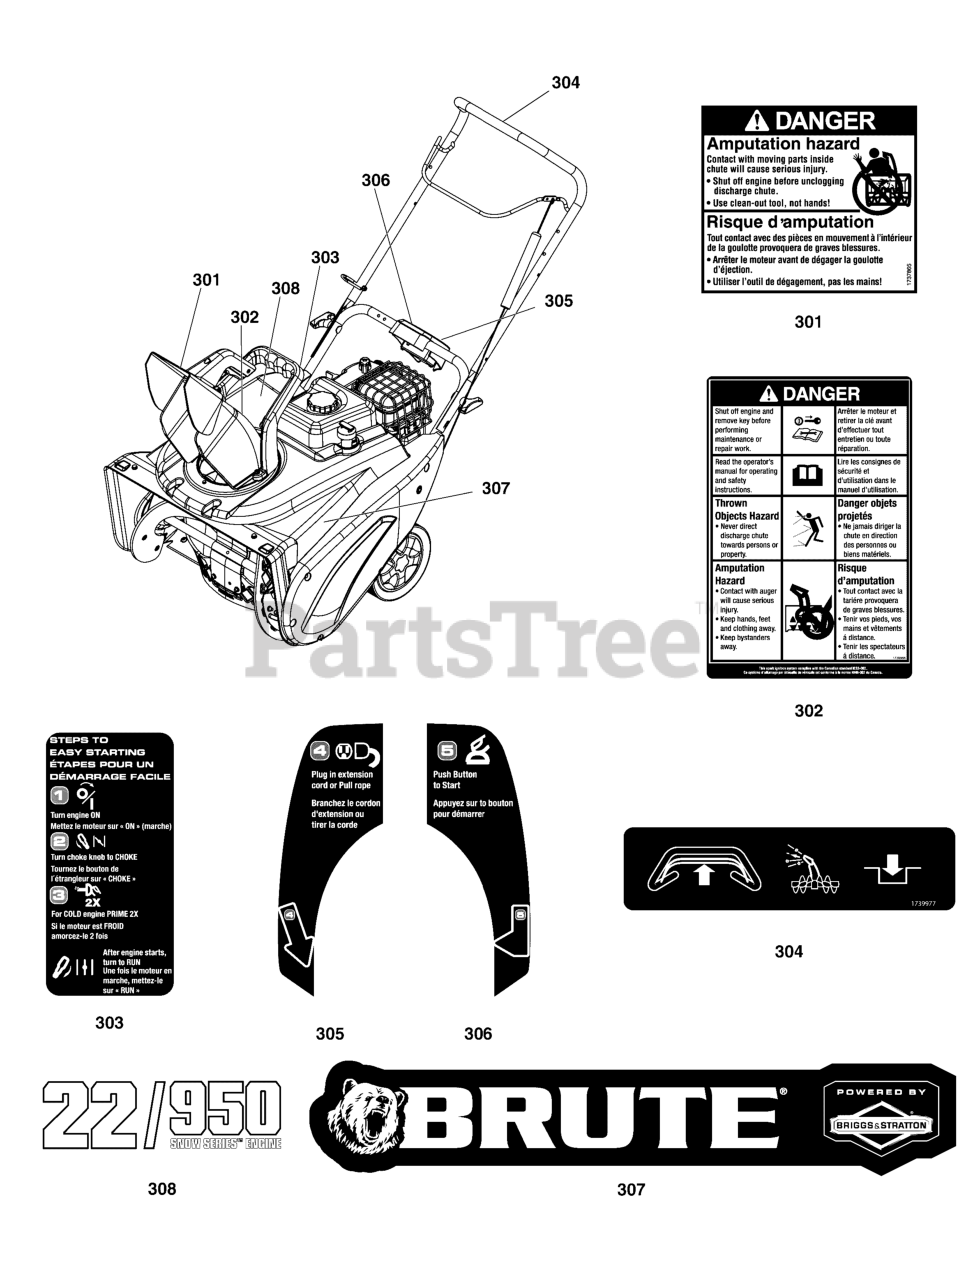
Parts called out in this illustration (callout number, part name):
301	DECAL, Danger Chute Warning, FR/ENG
302	DECAL, Chute, FR-EN
303	DECAL, 1-2-3 Start, FR-EN
304	DECAL, Bail Engagement
305	DECAL, 4, START, FR-EN
306	DECAL, 5, START, FR-EN
307	DECAL, Brute Logo
